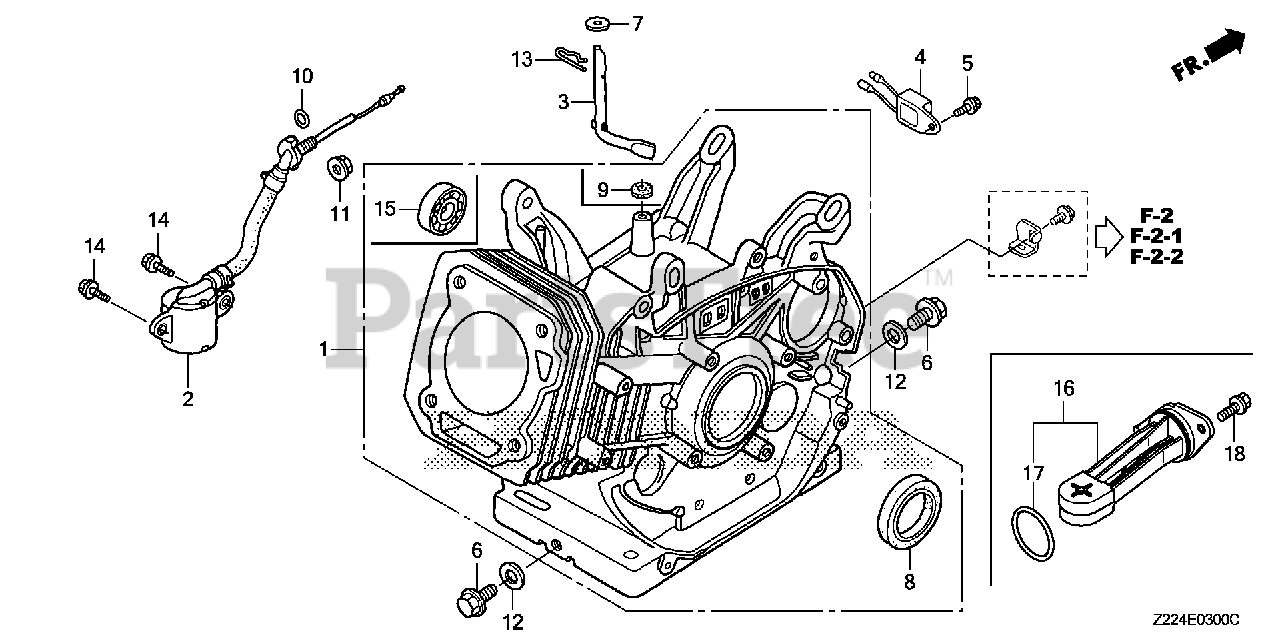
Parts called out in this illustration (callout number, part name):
1	CYLINDER ASSY. (ALERT)
2	SWITCH ASSY., OIL LEVEL
3	SHAFT, GOVERNOR ARM
4	ALERT UNIT, OIL
5	BOLT, FLANGE (6X12) (CT200)
6	BOLT, DRAIN PLUG (12X15)
7	WASHER (8.2X17X0.8)
8	OIL SEAL (35X52X8)
9	OIL SEAL (8X14X5)
10	O-RING (13.5X1.5) (ARAI)
10	O-RING (14MM) (NOK)
11	NUT, FLANGE (10MM)
12	WASHER, DRAIN PLUG (12MM)
13	PIN, LOCK (10MM)
14	BOLT, FLANGE (6X12)
15	BEARING, RADIAL BALL (6202)
